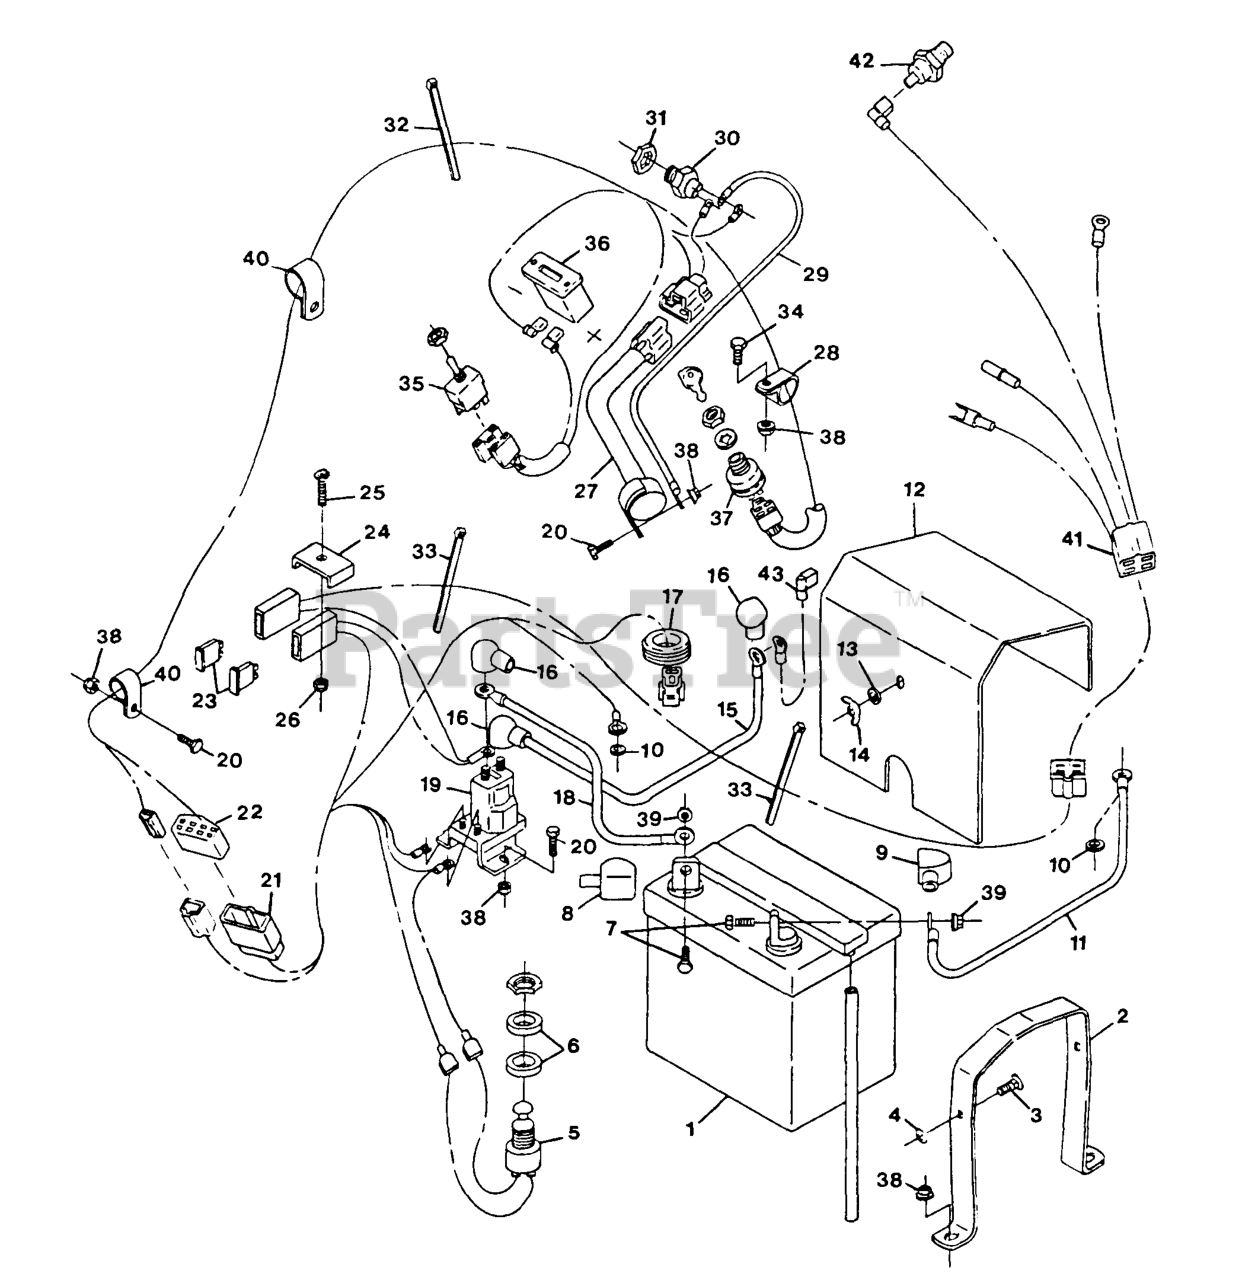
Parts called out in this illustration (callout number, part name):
1	Battery, 12v Manifold
2	STRAP,BATTERY HOLDDOWN
3	BOLT-CARR
4	NUT-RETAINING
5	SWITCH,PUSH BUTTON
9	INSULATOR, BATTERY -
11	WIRE-GROUND
14	NUT-WING
16	INSULATOR-SOLENOID
17	GROMMET
21	HARNESS,WIRING HYDRO
23	FUSE-BLADE TYPE, 20 AMP
24	CLIP-FUSE BLOCK PLTD
28	CLIP-LOOM
30	SWITCH,OPERATOR CNTRL
32	TIE-PLASTIC
33	TIE-CABLE
35	SWITCH,W/TERM CLIPPD
36	METER-HOUR
37	SWITCH,IGNITION
40	CLIP-LOOM
41	WIRHRNS,ENG ADAPTER
42	SWITCH-OIL PRESSURE
